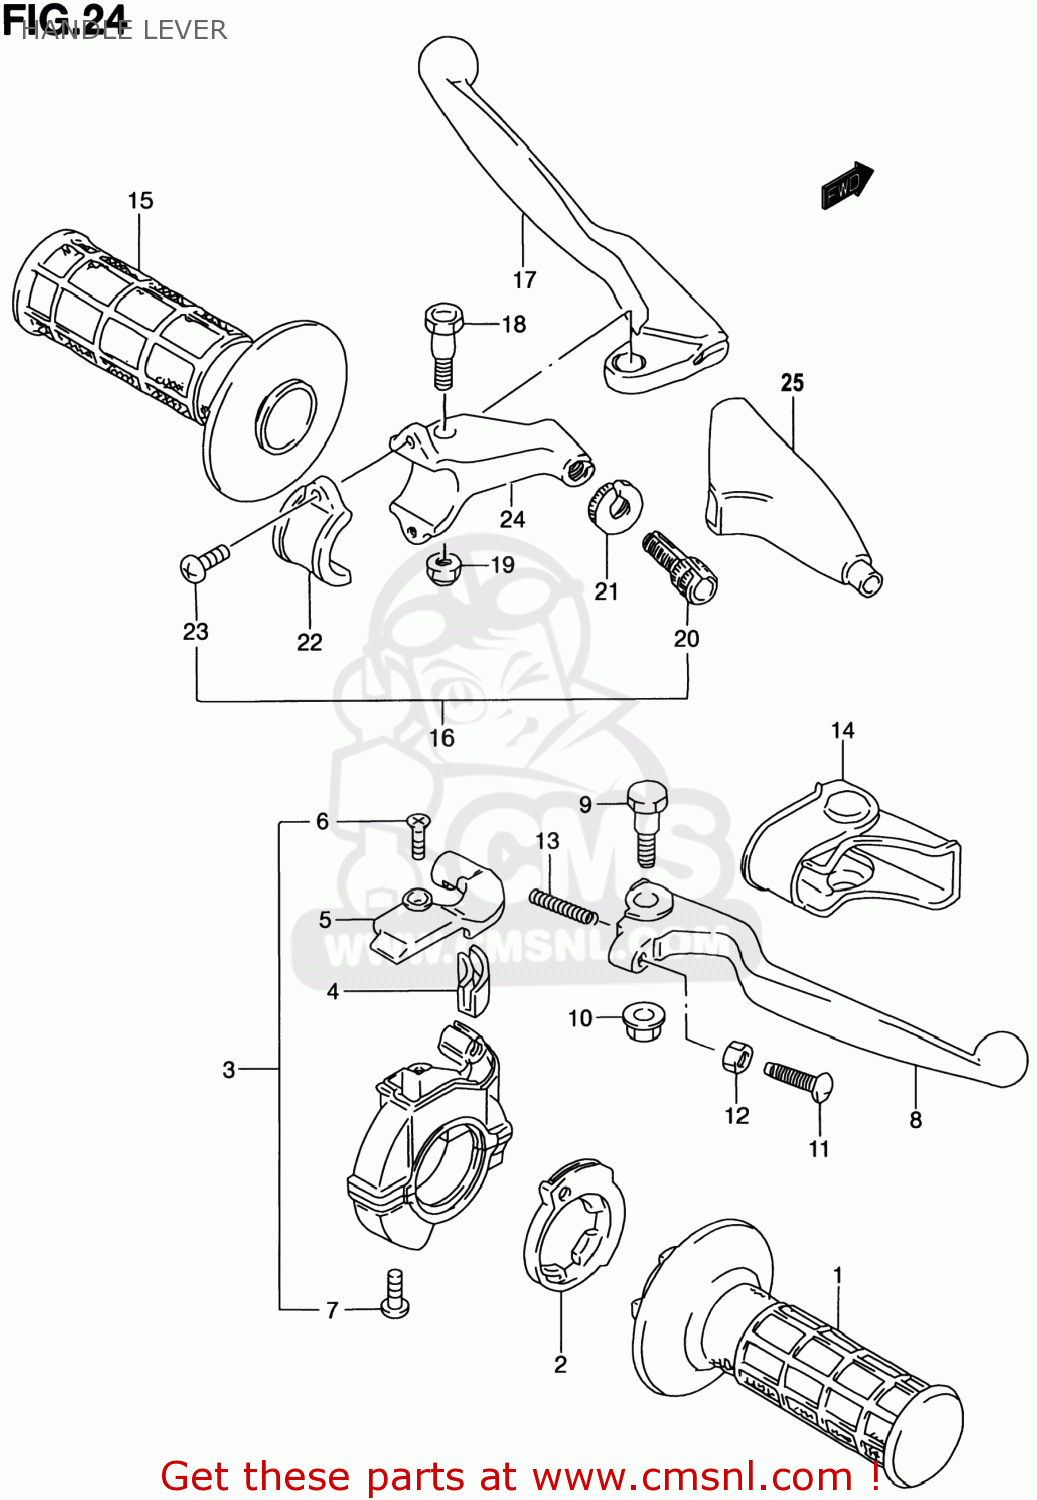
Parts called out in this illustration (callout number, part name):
1	GRIP,THROTTLE
2	ROTOR,THROTTLE GRIP
3	CASE ASSY,THROTTLE
4	GUIDE PIECE,THROTTLE
5	COVER,THROTTLE CASE
6	SCREW,UPPER
7	SCREW
8	LEVER,BRAKE
9	BOLT,BRAKE LEVER
10	NUT
11	BOLT,ADJUST
12	NUT
13	SPRING,RETURN
14	COVER,BRAKE LEVER
15	GRIP,L
16	LEVER ASSY,CLUTCH
17	LEVER,CLUTCH
18	BOLT,LEVER
19	NUT 6MM
20	ADJUSTER,CABLE
21	NUT,CABLE ADJUSTER
22	BRACKET,CLUTCH LEVER HOLDER
23	SCREW(5X14)
24	HOLDER,CLUTCH LEVER
25	COVER,CLUTCH LEVER
